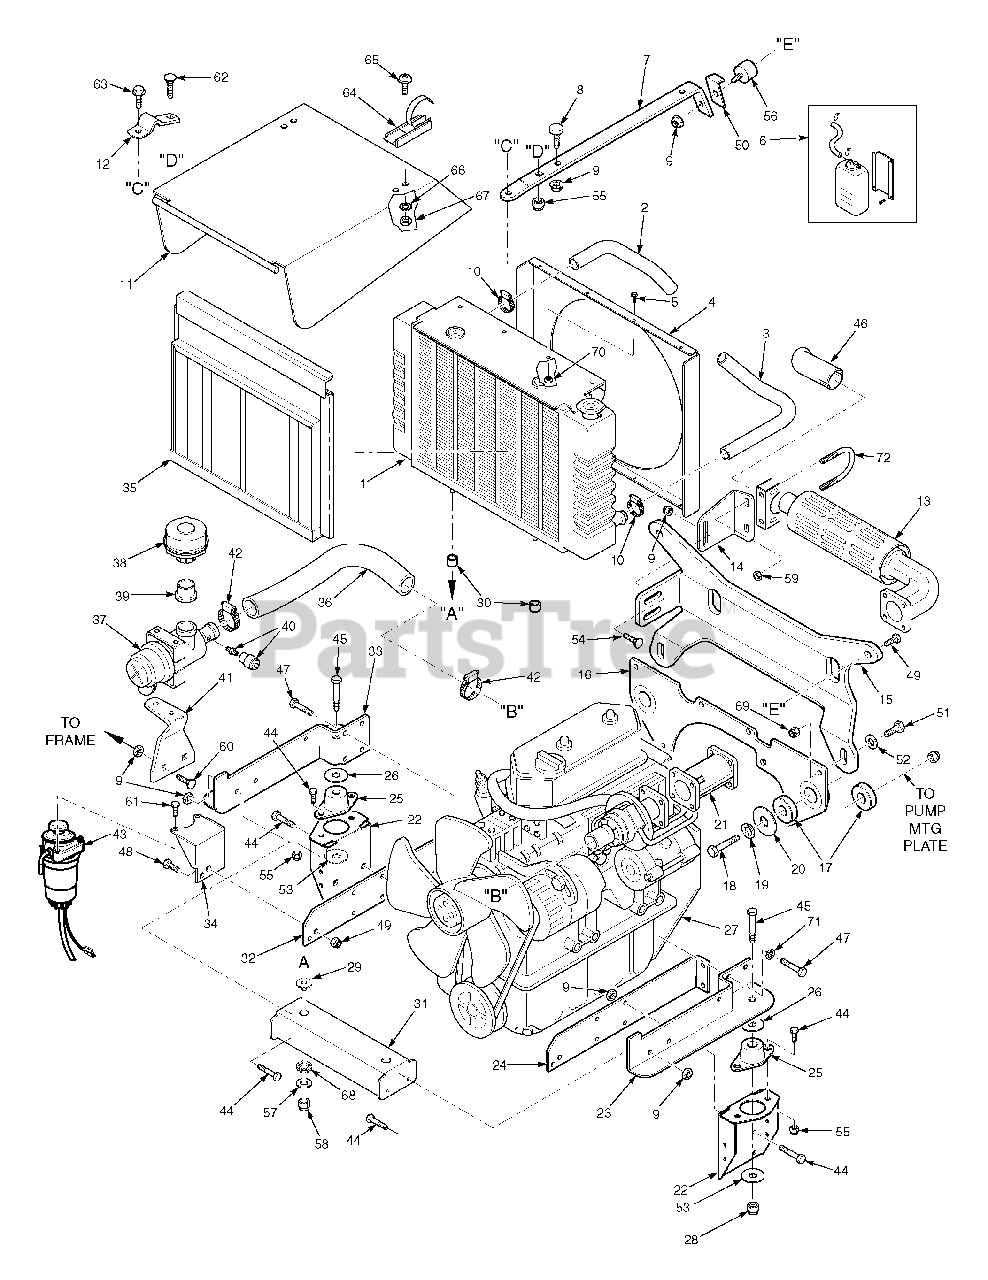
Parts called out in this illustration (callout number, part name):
1	Radiator
2	Hose, Upper Radiator
3	Hose, Lower Radiator
4	Shroud, Fan
5	Screw. #10-32 x 1/2"
6	Coolant Tank Assembly w/hose (Not Avail. Through Scag, Contact Briggs & Stratton)
7	Support Bracket, Hood
8	Bumper, Rubber
9	Nut, Serrated Flange 5/16-18
10	Clamp, 1-1/2" Dia.
11	Hood Weldment
12	Hinge, Hood
13	Muffler with Guard
14	Brace, Muffler Support
15	Mounting Bracket, Hood
16	Mounting Bracket Weldment, Rear Engine Mount
17	Engine ISO Mount, Rear
18	Bolt, Hex Head 1/2-13 x 3-1/2"
19	Lockwasher, 1/2" Spring
20	Flatwasher, 1/2-.531 x 2.0 x .25
21	Manifold Extension, Exhaust
22	Mounting Bracket, Engine
23	Mounting Bracket Weldment, Engine L.H.
24	Mounting Bracket, Engine L.H.
25	Engine ISO Mount, Front
26	Flatwasher, 1/2-.531 x 2.0 x .25
27	Engine, Briggs & Stratton 31hp Diesel (Spec. # )
28	Nut, Elastic Stop 1/2-13
29	Bushing, Radiator Isolator
30	Bushing, Radiator ISO Mount
31	Support Bracket, Radiator
32	Mounting Bracket, Engine R.H.
33	Mounting Bracket Weldment, Engine R.H.
34	Mounting Bracket, Water Seperator
35	Debris Screen
36	Hose, Air Intake
37	Air Cleaner Assembly w/mounting Band
38	Pre Cleaner, Engine Air
39	Adapter, Pre Cleaner
40	Indicator, Air Cleaner
41	Bracket, Air Cleaner
42	Clamp, Hose 2-1/2" Dia.
43	Fuel Filter, Water Seperator (Not Avail. Through Scag)
44	Bolt, Hex Head 5/16-18 x 3/4"
45	Bolt, Hex Head 1/2-13 x 2-1/2"
46	Elbow, Exhaust
47	Bolt, Hex Head M8-1.25 x 3mm
48	Bolt, Hex Head 3/8-16 x 1-1/4"
49	Bolt, Hex Head 5/16-18 x 3/4"
50	Catch Bracket, Hood Latch
51	Bolt, Hex Head 3/8-16 x 1-1/4"
52	Flatwasher, 3/8-.391 x .938 x .105
53	Flatwasher, 1/2-.531 x 2.13 x .1345
54	Bolt, Carriage 5/16-18 x 1"
55	Nut, Elastic Stop 5/16-18
56	Rubber Isolator
57	Flatwasher, 7/16-.469 x 2.0 x .1345
58	Nut, Center Lock 7/16-14
59	Nut, Elastic Stop 5/16-18
60	Bolt, Carriage 5/16-18 x 3/4"
61	Bolt, (Not Available Through Scag, Contact Briggs & Stratton)
62	Bolt, Carriage 5/16-18 x 1"
63	Bolt, Hex Head 5/16-18 x 3/4" Serr. Flange
64	Latch, Hood
65	Screw, #10-32 x .375
66	Lockwasher, #10 Spring
67	Nut, #10
68	Ring, Isolator
69	Nut, Elastic Stop 3/8-16
70	Nut, Elastic Stop #10-32
71	Lockwasher, 5/16 Spring
72	Muffler Clamp 1-1/2" Dia.
